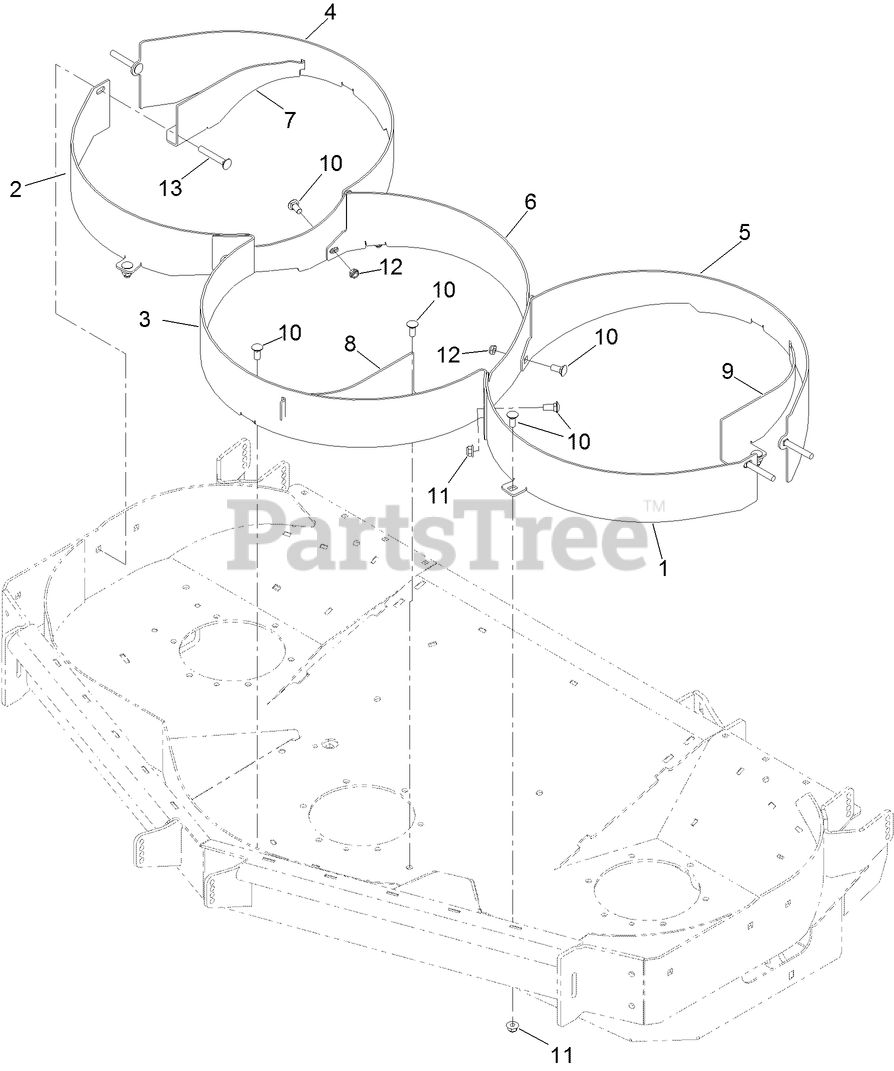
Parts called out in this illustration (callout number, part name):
1	BAFFLE-MULCH, FRONT RH
2	BAFFLE-MULCH, FRONT LH
3	BAFFLE-MULCH FRONT CENTER
4	BAFFLE-MULCH REAR LH
5	BAFFLE-MULCH REAR RH
6	BAFFLE-MULCH, REAR CENTER
7	BAFFLE-KICKER, LH
8	BAFFLE-KICKER, FRONT CENTER
9	BAFFLE-KICKER, RH
10	BOLT-CARR
11	NUT-HF, NI
13	SCREW-CARR
